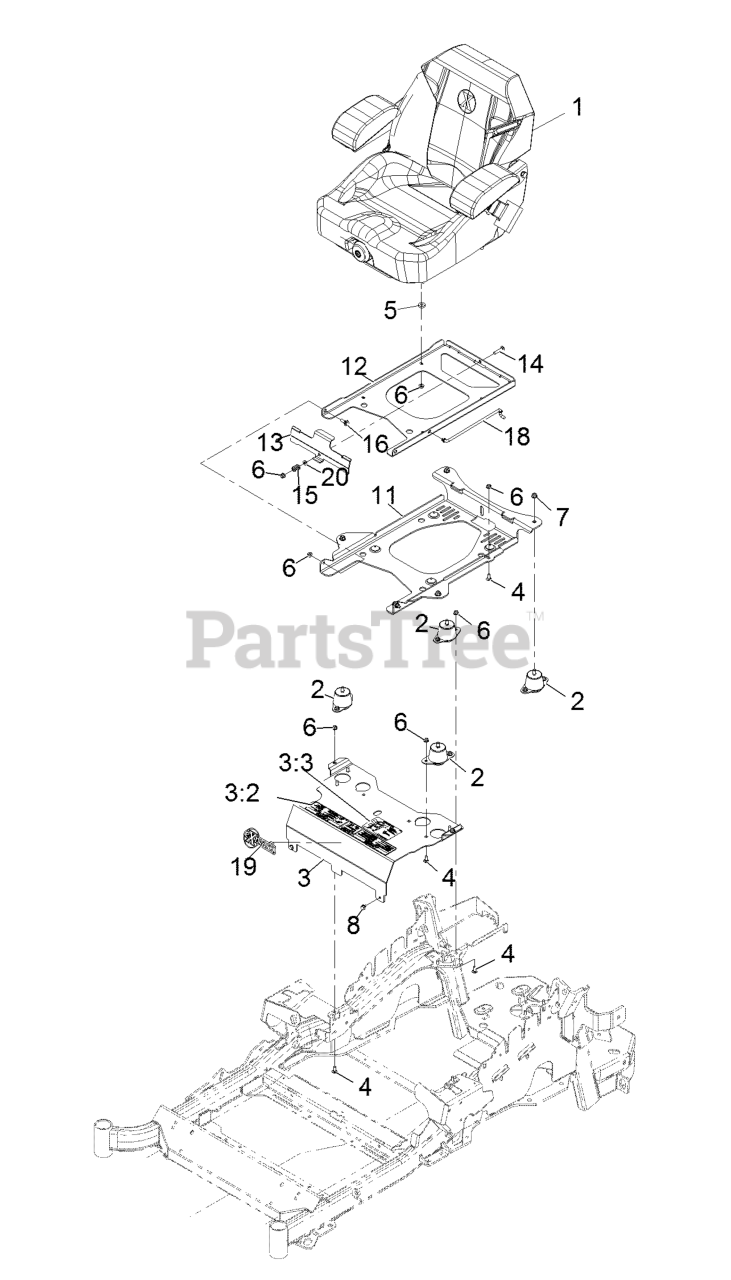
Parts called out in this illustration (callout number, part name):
1	KIT-SUSPENSION SEAT
2	ISOLATOR-SEAT
3	MOUNT-SEAT
3:2	DECAL-CONSOLE
3:3	DECAL-SERVICE AID
4	SCREW-CARR
6	NUT-HF, NI
7	NUT-HF, NI
11	PLATE-TILT, SEAT SUPPORT
12	PLATE-FRAME, SEAT
13	PLATE-LATCH, SEAT
14	BOLT-CARR
15	SPRING-COMPRESSION
16	SCREW-SHOULDER
18	ROD-PROP
20	WASHER-PLAIN
